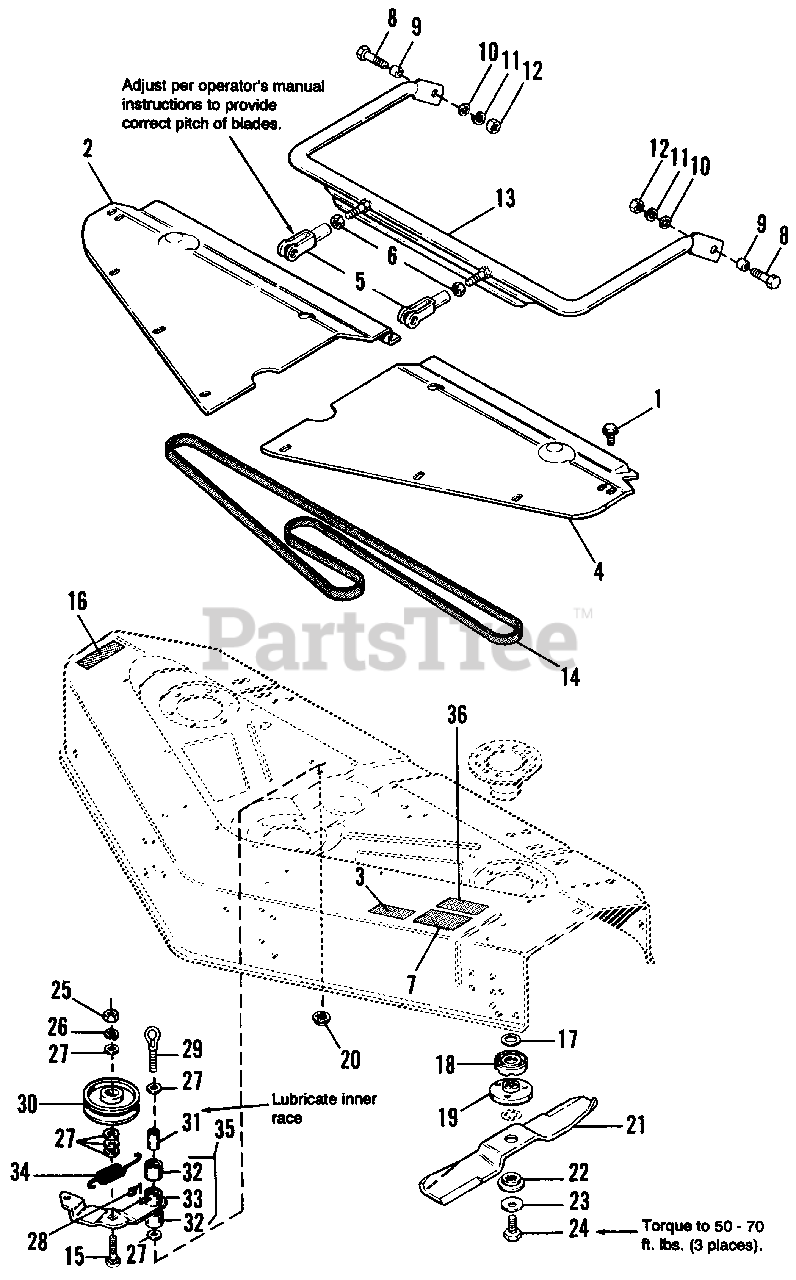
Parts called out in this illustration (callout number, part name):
1	SCREW, Hex, Taptite, 1/4-20 x 3/8
2	COVER, R.H. (Orange)
2	COVER, R.H. (Black)
3	DECAL, Belt Installation, Adjustment
4	COVER. L.H. (Orange)
4	COVER. L.H. (Black)
6	NUT, Hex, Jam, 1/2-20
7	DECAL, Danger, Deflector in place
8	CAPSCREW, Hex Hd., 1/2-13 x 1-1/4
10	WASHER, Plain, 7/16
11	LOCKWASHER, 1/2
12	NUT, Hex, Full, 1/2-13
14	V-BELT, Arbor Drive
15	CARRIAGE BOLT 3/8-16 x 1-1/4
16	DECAL, Danger, Rotating Blade
17	WASHER, Shim
18	SHIELD, Grass
19	ADAPTER, Blade
20	NUT, Hex, Flange Whizlock, 3/8-16
21	BLADE, 48" Mower
22	WASHER, Spline
23	WASHER, Spring
24	CAPSCREW, Hex Hd., 7/16-14 x 1
25	NUT, Hex, Jam, 3/8-16
26	LOCKWASHER, 3/8
27	WASHER, Plain, 13/32
28	FITTING, Grease, 1/4-28
30	PULLEY ASSY., Idler
35	LEVER ASSY., Idler (lncl. Ref. Nos. 32 & 33)
36	DECAL, Cutting Width, 48"
